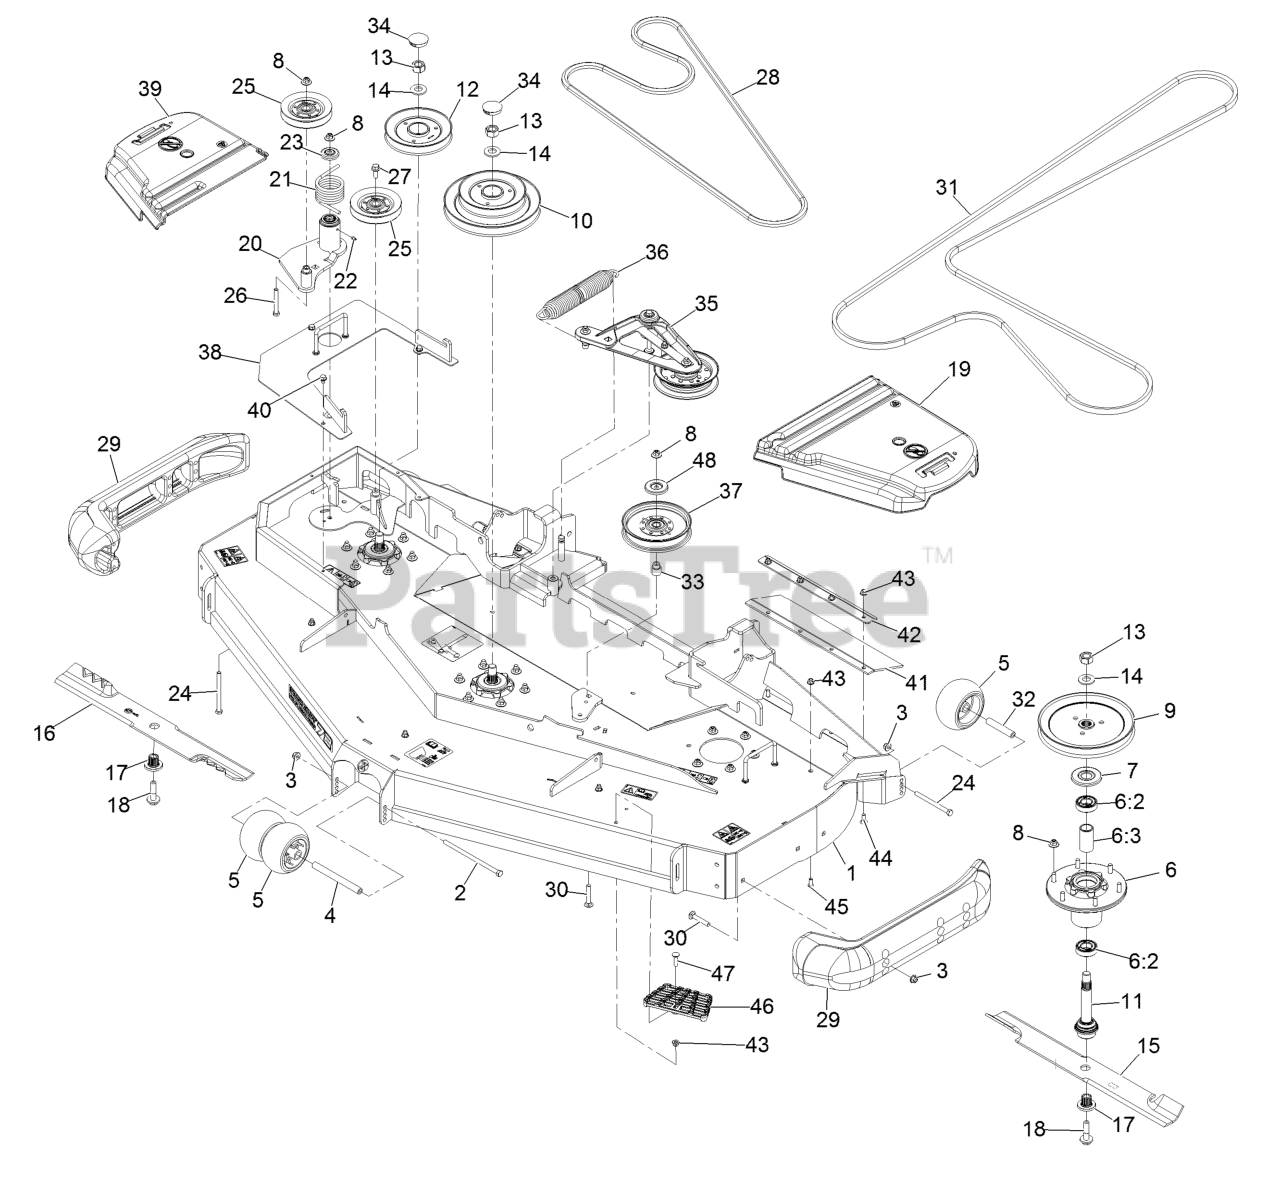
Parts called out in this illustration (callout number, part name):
1	Deck-Rd72 Nlz, W/Decals
2	Screw-HH 3/8-16 X 7 3/8
3	Nut-Nyloc 3/8-16 Flg
4	Spacer-Wheel
5	Roller-Scalp, Anti
6	ASM-Cutter Hsg With Bearings
6:2	Bearing-Ball
6:3	Spacer-Bearing
7	Guard,Bearing Top .989
8	Nut-Nyloc 3/8-16 Flg
9	Sheave,Blade Drive 8.74
10	Sheave, Double 72Rd
11	ASM-Spindle And Seal
12	Sheave-Rd Rev Drive Series 4
13	Nut-Hex
14	Washer-Spring Disc 3/4
15	Blade, Low Lift (72")
15	Blade, Notched (72")
15	Blade-Extreme 2, 24.50"
16	Blade-Low Lift 24.50, Rd72
16	Blade-Extreme 2-24.50, Rd72
17	Bushing, Splined
18	Screw-Sems 1/2-20 X 2.19
19	Cover-Belt, LH
20	Idler ASM
21	Spring-Torsion
22	Zerk-1/4-28 Str
23	Guard-Top
24	Screw-HH 3/8-16 X 4-1/2
26	Screw-HH 3/8-16 X 2 3/4
27	Screw-HH Flg 3/8-16 X 1
29	Skid-Bumper, Deck
30	Bolt-Carriage 3/8-16 X 2
31	Belt
32	Tube-Spanner
33	Bushing, Idler
34	Plug,Black Nylon 1.75
35	Deck Idler ASM
36	Spring-Extension
37	Idler-Pulley, Flat 6.00X1.00
38	Cover-Reverse Drive
39	Cover-Belt, RH
40	Screw-HWH 5/16 X 1/2 Tf
41	Guard-Tire
42	Support-Outer Flap
43	Nut-Nyloc 5/16-18 Flg
44	Bolt-Carriage 5/16-18 X 7/
45	Screw-Button Head 5/16-18 X 3/4
46	Step-Deck
47	Bolt-Carriage 5/16-18 X1/4
48	Shield-Dust
